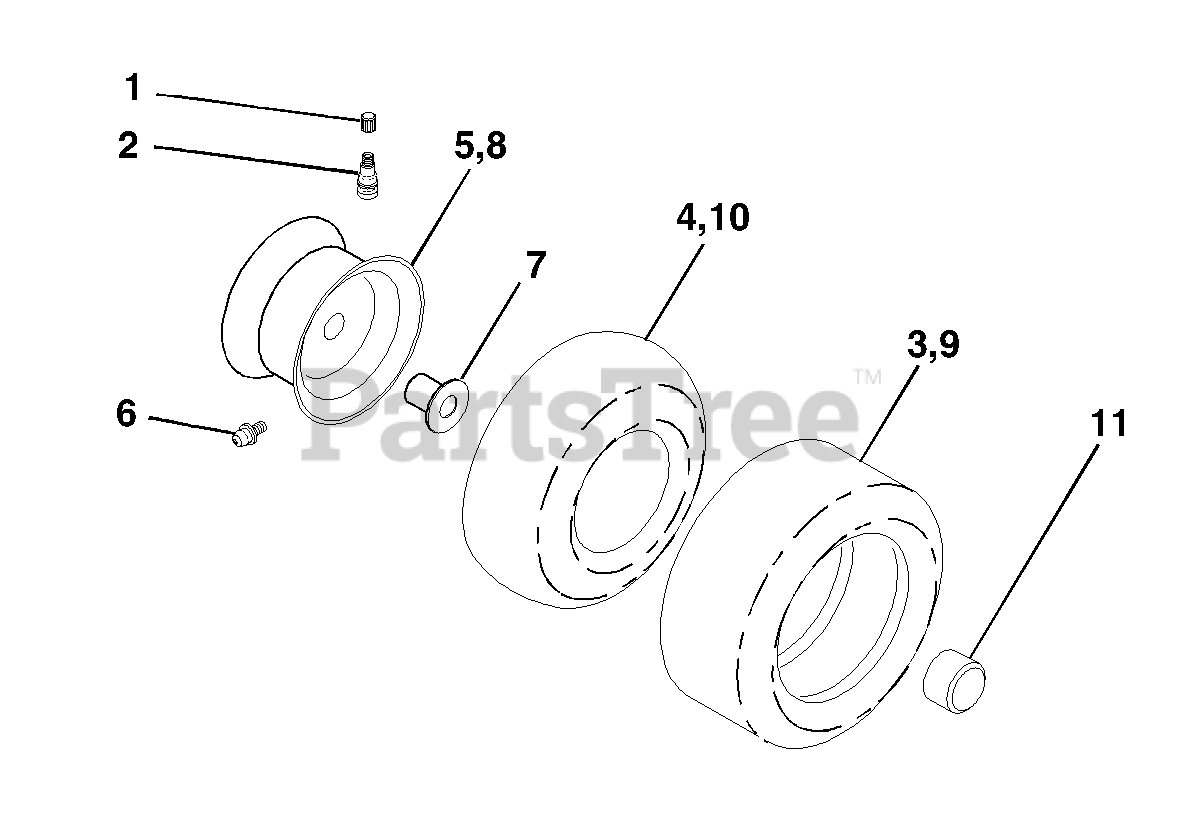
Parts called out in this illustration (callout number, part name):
1	Cap Valve Tire
2	Stem Valve
3	Tire F Ts 15 X 6 0 - 6 Service
4	Tube Front
5	Rim Asm 6" front White Service
6	Fitting Grease
7	Bearing Flange
8	Rim Asm 8"rear White Service
9	Tire R Ts 18x9.5-8 C Service
10	Tube Rear
11	Cap Axle Blk 1 50 X 1 00
